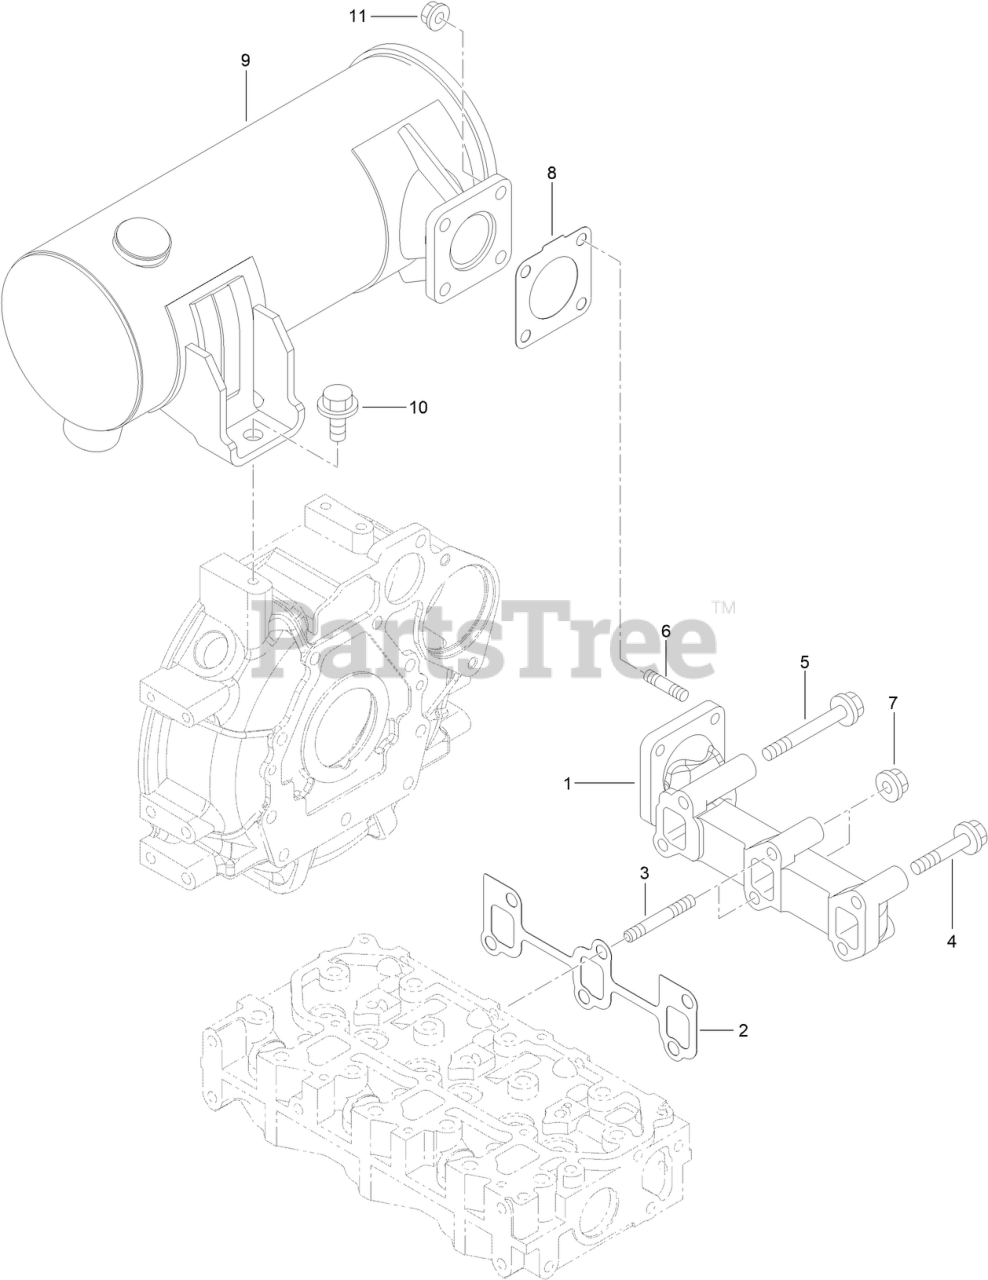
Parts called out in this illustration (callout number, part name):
1	MANIFOLD, EXHAUST
2	GASKET-EXH MANIFOLD
3	BOLT-STUD
8	GASKET-SILENCER
9	MUFFLER
